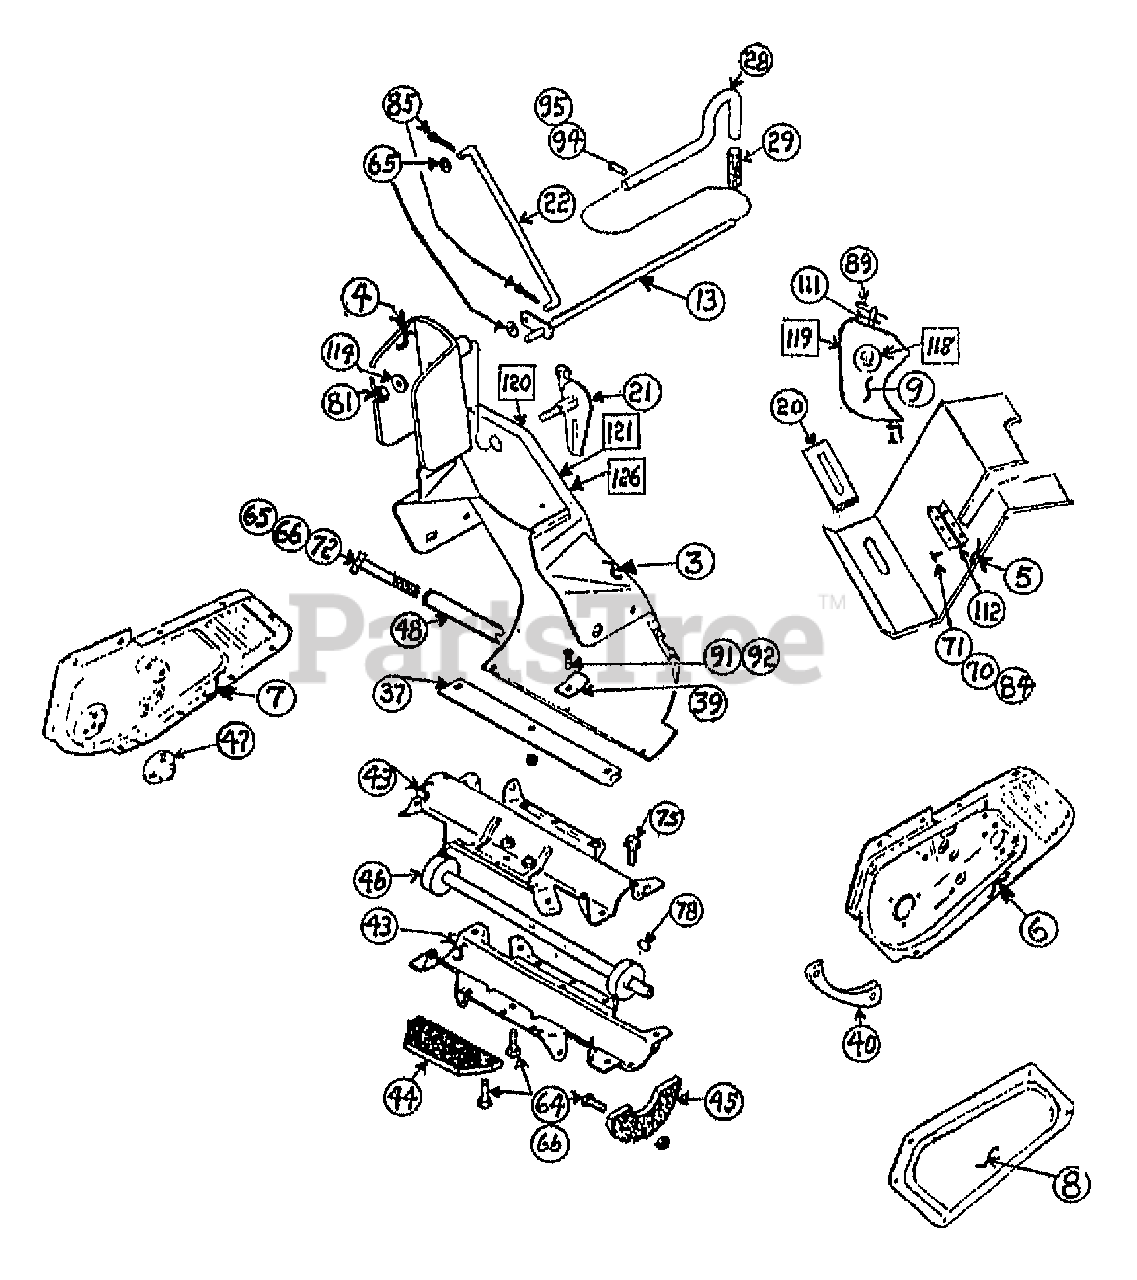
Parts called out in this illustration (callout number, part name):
3	WRAP SHEET W/DECALS
4	DEFLECTOR-VANE
5	MAIN GUARD W/DECAL
6	ASSM-SIDE PLATE LH
7	ASSM-PLATE RH
9	GUARD-DRIVE W/DECAL
10	BELT-V UPR DR SNOWBLOW
11	BELT-AUGER
12	BRKT-LOCKING PNT
13	DEFLECTOR-ROD WELD
15	SHAFT PICK-UP
16	BRKT-MOUNTING
18	PULLEY-ENGINE PICK-UP
19	PULLEY-AUGER DRIVE
20	SHIELD-WEATHER
21	ASSM-PIVOT VANE
22	ROD-LINKAGE
23	BRKT-MOUNTING WELD
24	HOLDER-IDLER WELD
25	PULLEY-IDLER
26	ASSM-IDLER PLATE
27	PLATE-MOUNTING
28	HANDLE-VANE CONTROL
29	GRIP-VANE CONTROL
30	PULLEY-ENGINE 4L
31	SPRING-COMPRESSION
32	ASSM-IDLER PULLEY
33	BUSHING-PIVOT
34	PULLEY-AUGER
35	STOP-OVERCENTER
36	GUIDE-BELT
38	ASSM-IDLER ARM
39	SPRING-AUGER STOP
42	ASSM-RECOIL GUARD
43	PLATE-AUGER
46	SUPPORT-AUGER
47	ASSM-BEARING
49	ASSM-SWITCH
50	COVER-CARB W/DECAL
51	D SPACER-IDLER
52	BOLT
53	WASHER
54	NUT
55	BOLT
56	WASHER
57	WASHER
58	BOLT
59	WASHER
60	NUT
61	WASHER
63	SCR-HH 5/16-18 X .20 STH ZP
64	BOLT
65	WASHER
66	NUT
67	RING-SNAP
68	WASHER-FLAT 3/4
69	SCR-RD HD #10-24 X 3/4
70	WASHER
71	NUT
72	SCR-HH 1/4-20 X 6
75	SCR-HEX TYPE A #10-.500
76	BOLT-HH 1/4-28 X 3/4
77	WASHER-1.06 X .25 X .067
78	KEY-WOODRUFF 1/8 X 1/2
79	BOLT
80	NUT
81	NUT
83	SCR-SHAKE PR 1/4-15 X 3/4
84	SCR-RH M10-24 X .50 ZP
86	CUSHION-6.74 5 LONG
87	CUSHION-3.75 LONG
88	KEY
89	PIN-HITCH ZP
90	KEY-.188 SQ X 1.25
91	SCR-HEX SOC FL #10-24
92	NUT
93	BRACE-SUPPORT
94	SCR-RD HD #8-32 X 5/8
95	NUT-LOCK #8-32
96	NUT
97	SCR-FLT HD 5/16-24
98	BOLT
99	PIN
102	LEVER-REMOTE CHOKE
103	WASHER
104	N KNOB-CHOKE LEVER
105	ENGINE STUD
106	SCR-HH 5/16-18X.63 G5
107	WASHER
110	CLAMP-CABLE
112	HINGE-SHROUD
113	WASHER
114	WASHER-FLAT 7/16 SAE
115	SCR-FLHH 5/16-24 X .75 ZP
117	DECAL-CARB COVER
118	DECAL-"CULTIVATOR-PLUS"
119	DECAL-WARN. BELT CVR
122	DECAL-DEFLECTOR PLT LT
123	DECAL-DEFLECTOR PLT RT
124	DECAL-ATTACH INST
126	DECAL-ANSI
